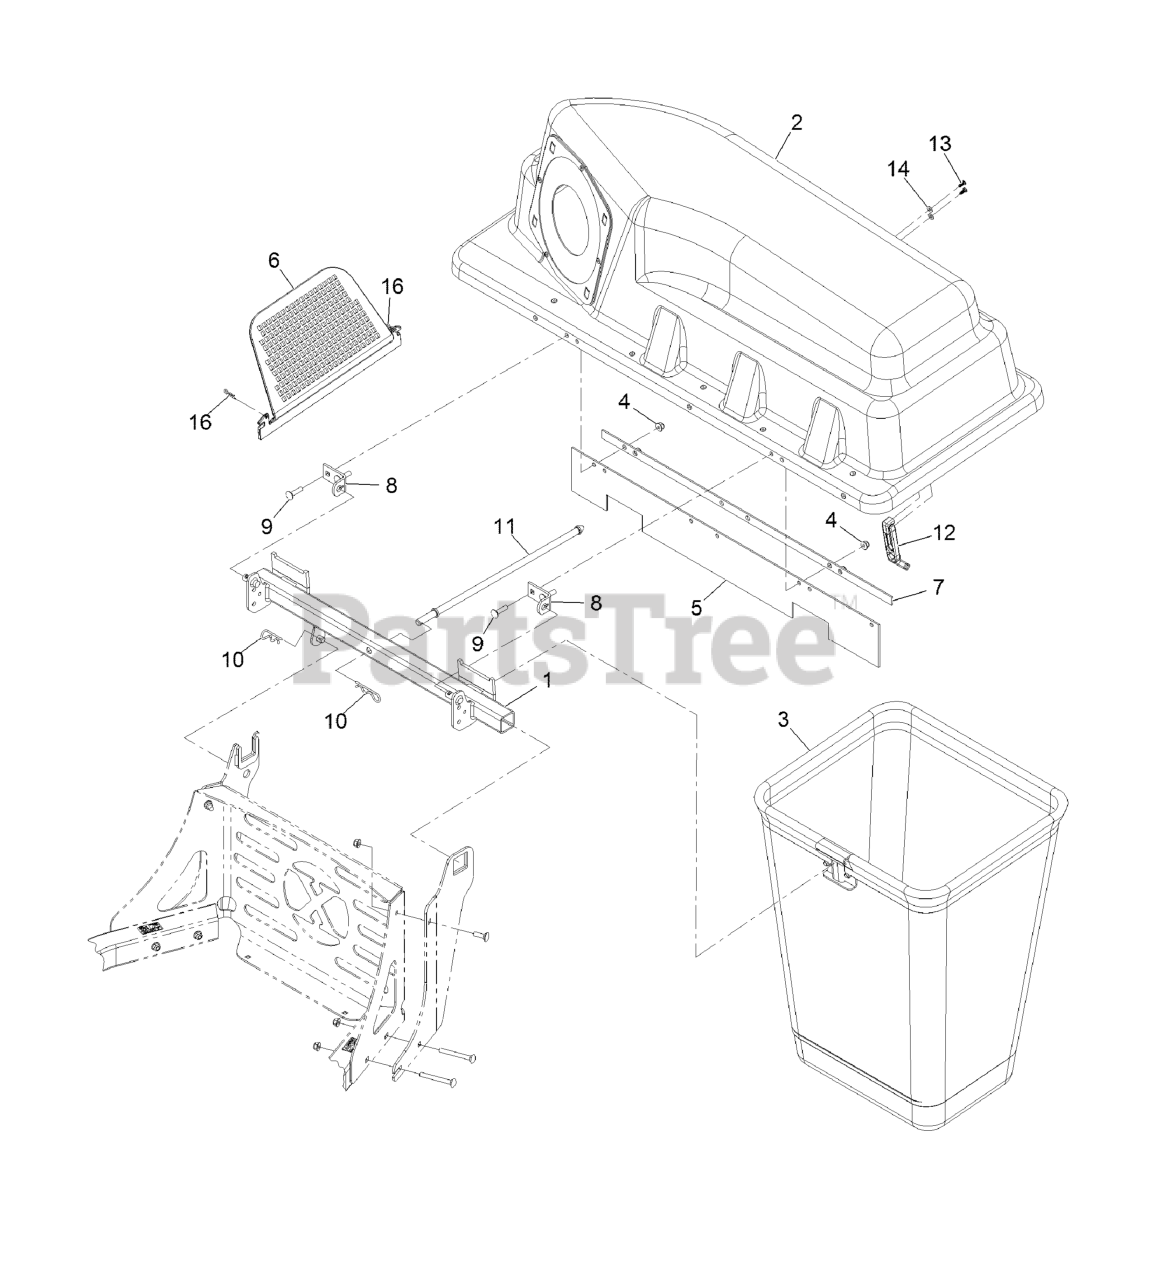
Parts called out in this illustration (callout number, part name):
1	FRAME PIVOT ASM
2	BAGGER HOOD ASM
3	BAG AND FRAME ASM
4	NUT-HF, NI
6	SCREEN-BAGGER
7	PLATE-BACKING
8	BRACKET-PIVOT, HOPPER
9	Bolt-Carriage 5/16-18 X 1 1/4
10	PIN-HAIR
11	ROD-HOLD DOWN, HOOD
12	LATCH-RUBBER
13	SCREW-PLASTITE
14	WASHER-FLAT
